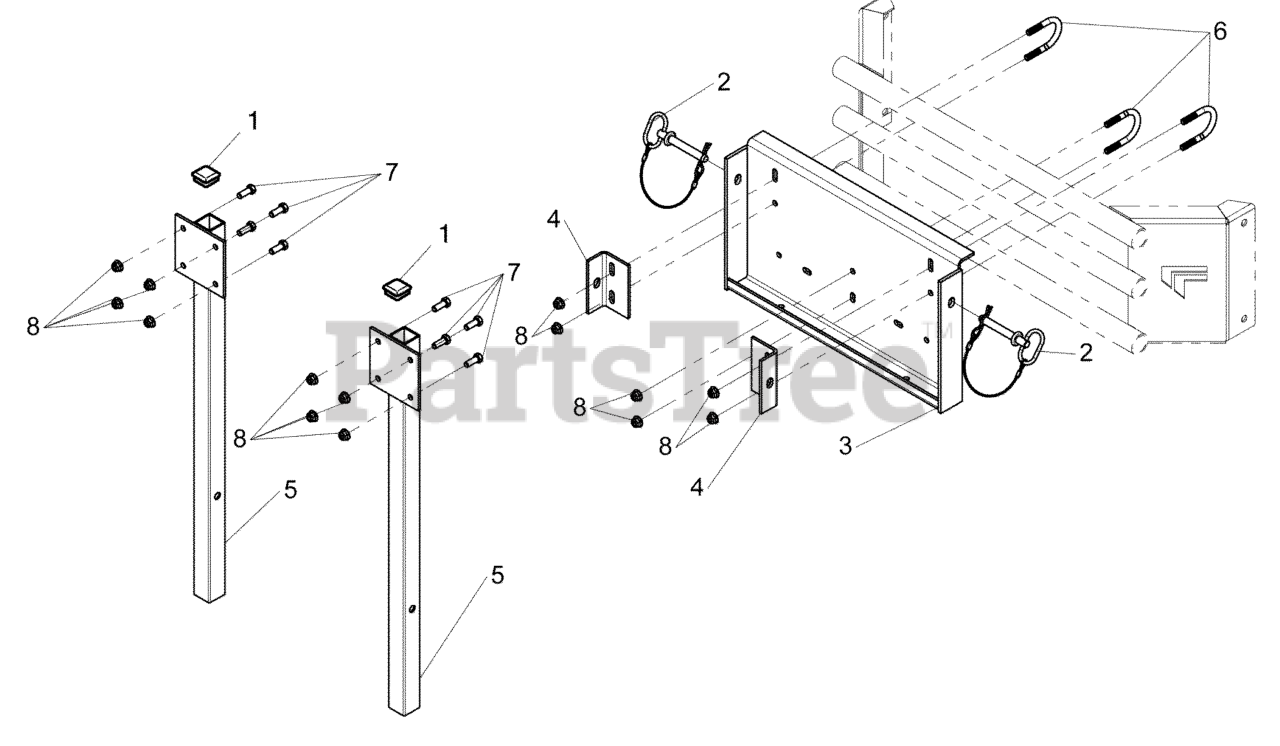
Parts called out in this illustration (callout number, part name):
1	CAP, PLASTIC, 1-1/2" X 1-1/2
2	PIN, HITCH, .50 X 3.25 W/ LAY
3	WELD, 3-BAG MOUNT, ALL - BLK
4	MOUNT, TAB, BLACK
5	WELD, MOUNT, POST - BLK
6	U-BOLT, 3/8 X 1-1/4
7	BOLT, 3/8-16 X 1" GD5 CZ
8	NUT, 3/8-16 HEX NYLOCK FLANGE
